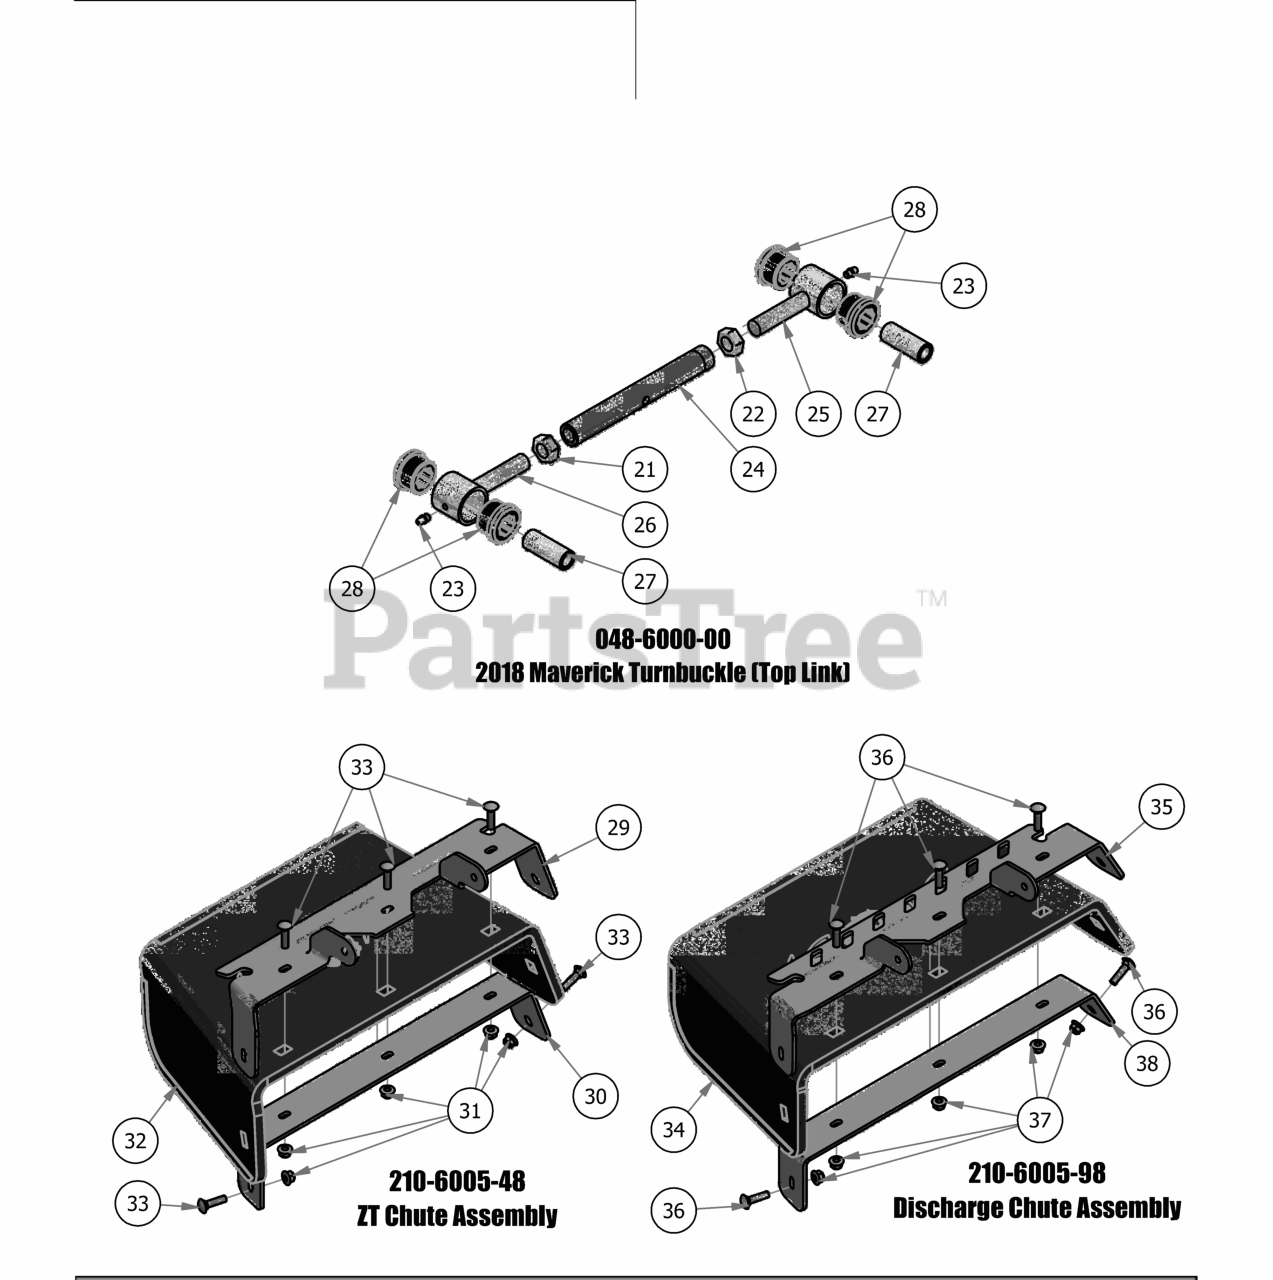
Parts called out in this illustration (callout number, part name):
21	NUT, 5/8-18
22	NUT, 5/8-18LH
23	1/4-28 Grease Fitting
24	2018 Maverick Toplink Body
25	2018 Maverick Bushing Retainer Left-Handed
26	2018 Maverick Bushing Retainer Right-Handed
27	2018 Maverick Bushing Sleeve
28	2018 Maverick Bushing
29	Discharge Upper Chute Bracket
30	Discharge Lower Chute Bracket
31	5/16" Nylon Flange Nut
32	Rubber Discharge Chute
33	5/16" x 1 1/4" Carriage Bolt
34	Rubber Discharge Chute
35	60" Discharge Chute Upper Hanger
36	5/16" x 1 1/4" Carriage Bolt
37	5/16" Nylon Flange Nut
38	60" Discharge Lower Bracket
